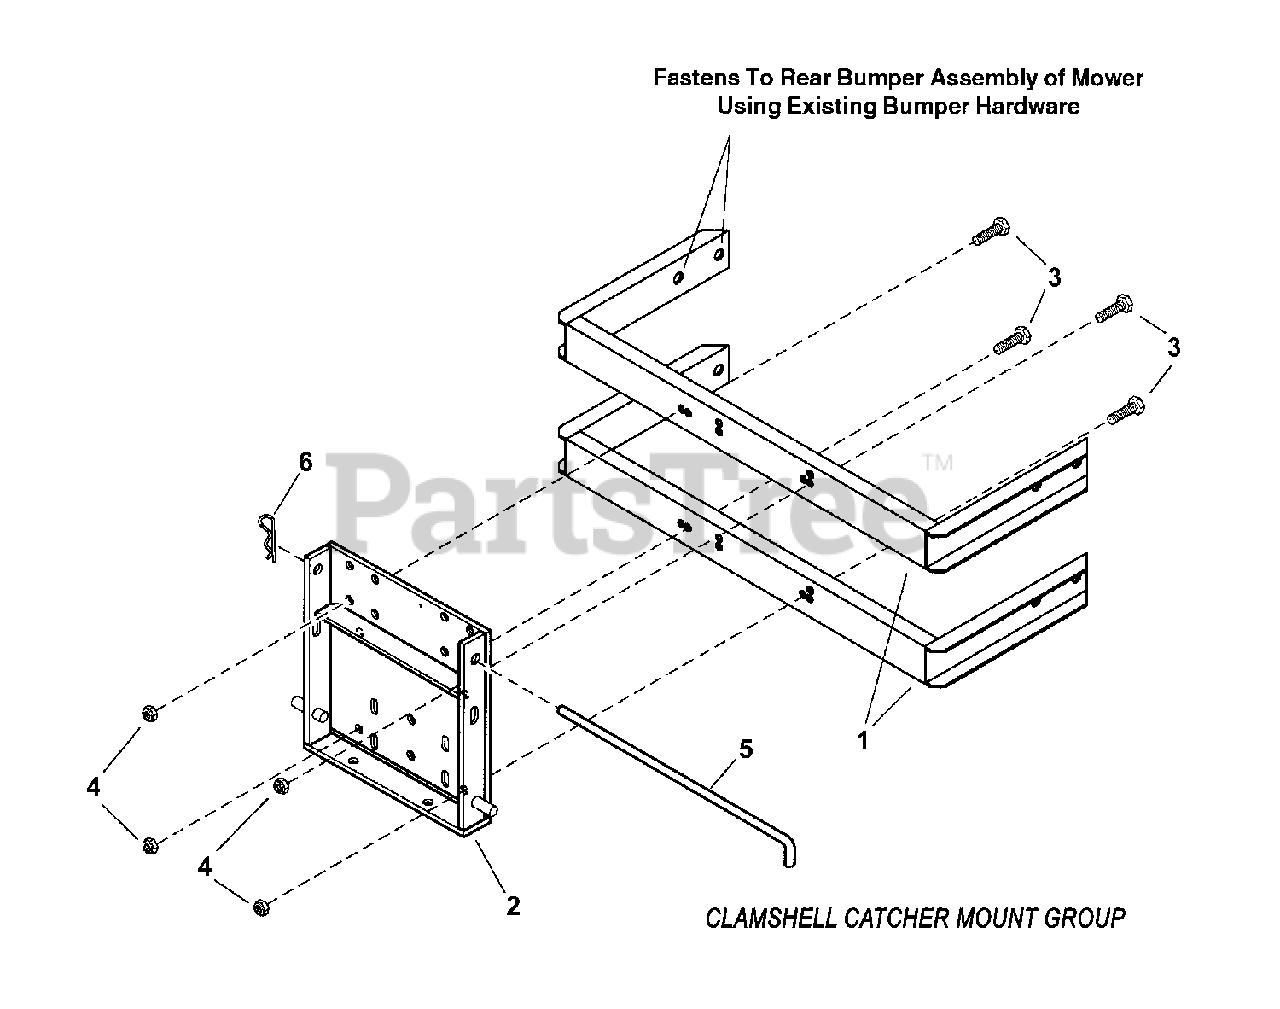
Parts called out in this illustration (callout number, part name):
1	STANDOFF, Bumper Mount (weldment)
2	WELDMENT, Bumper Mount Plate
3	SCREW, 5/16-18 x 3/4" Hex Head Cap, GR5
4	NUT, 5/16-18 Hex Flange Lock, GR5
5	ROD, Hitch
6	HAIR PIN, 3/32 x 1-1/2" Cotter
